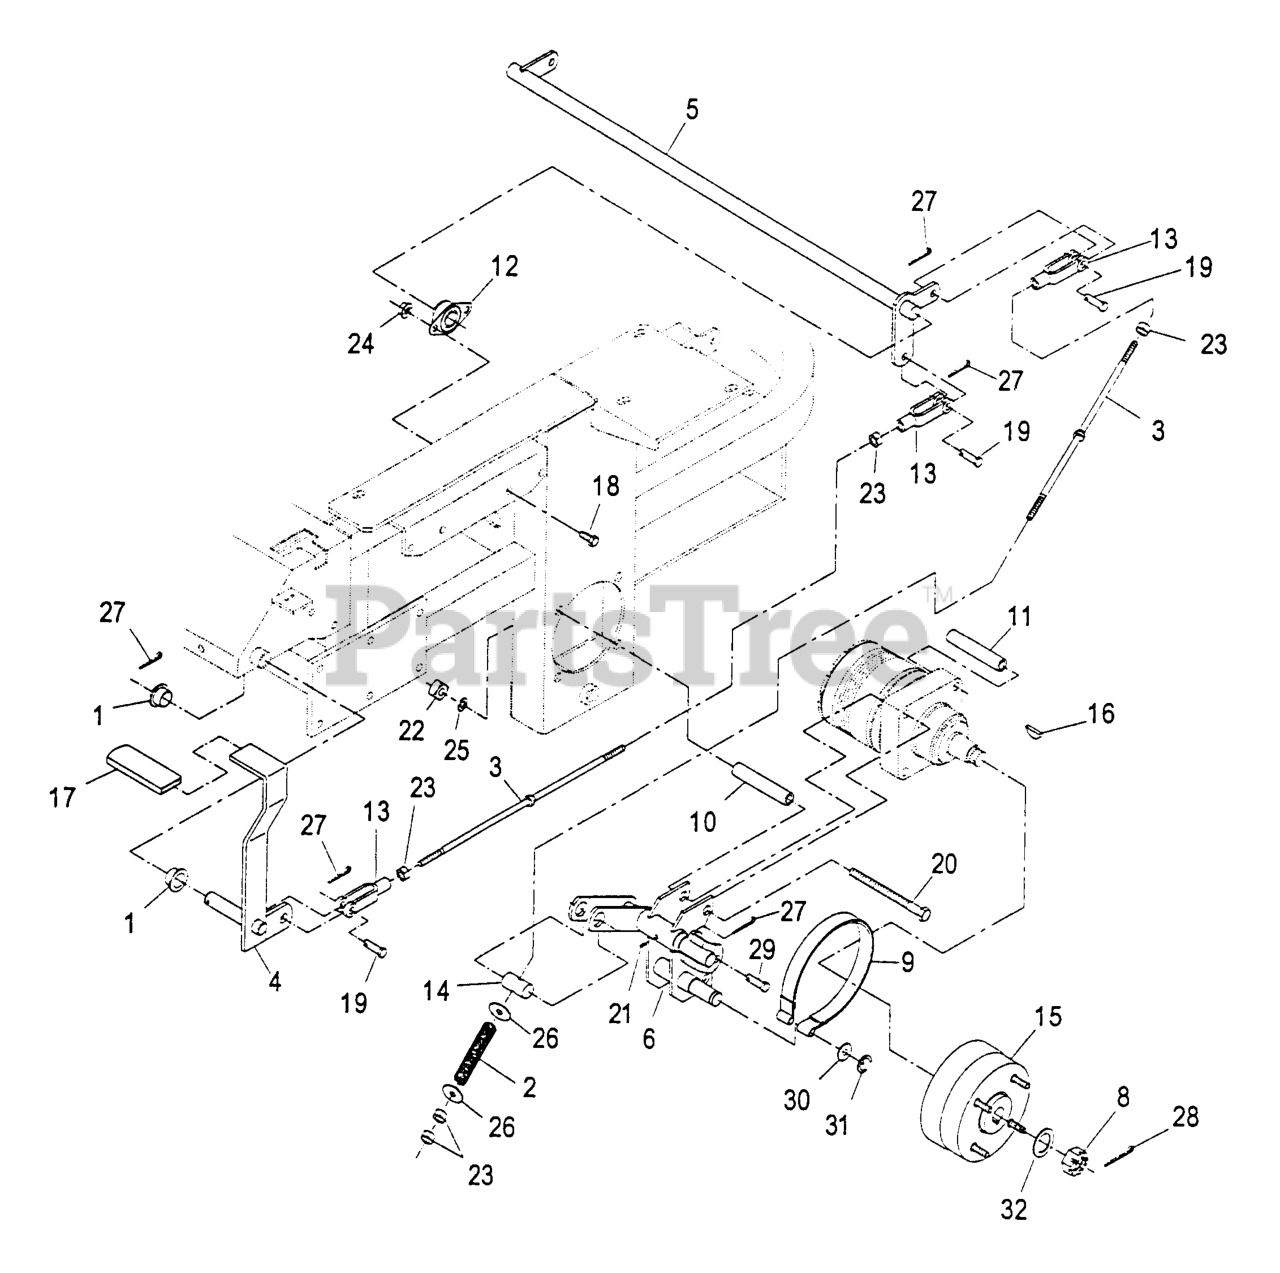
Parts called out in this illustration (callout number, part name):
1	BEARING-CONTROL
2	SPRING-BRAKE
3	ROD-BRAKE
4	BRAKE LEVER ASM
5	SHAFT-BRAKE
6	WLD,BRACKET LH 52
9	BAND,BRAKE
10	SPACER-WHEEL, SHORT
11	SPACER-WHEEL, LONG
12	BEARING-FLANGE, SIDE
13	YOKE-LINKAGE, BRAKE
14	PIN-TRUNION
17	GRIP-LEVER
19	PIN-CLEVIS
21	1481
28	PIN-COTTER
29	PIN,CLEVIS 3/8X2
32	WASHER-SPACER
